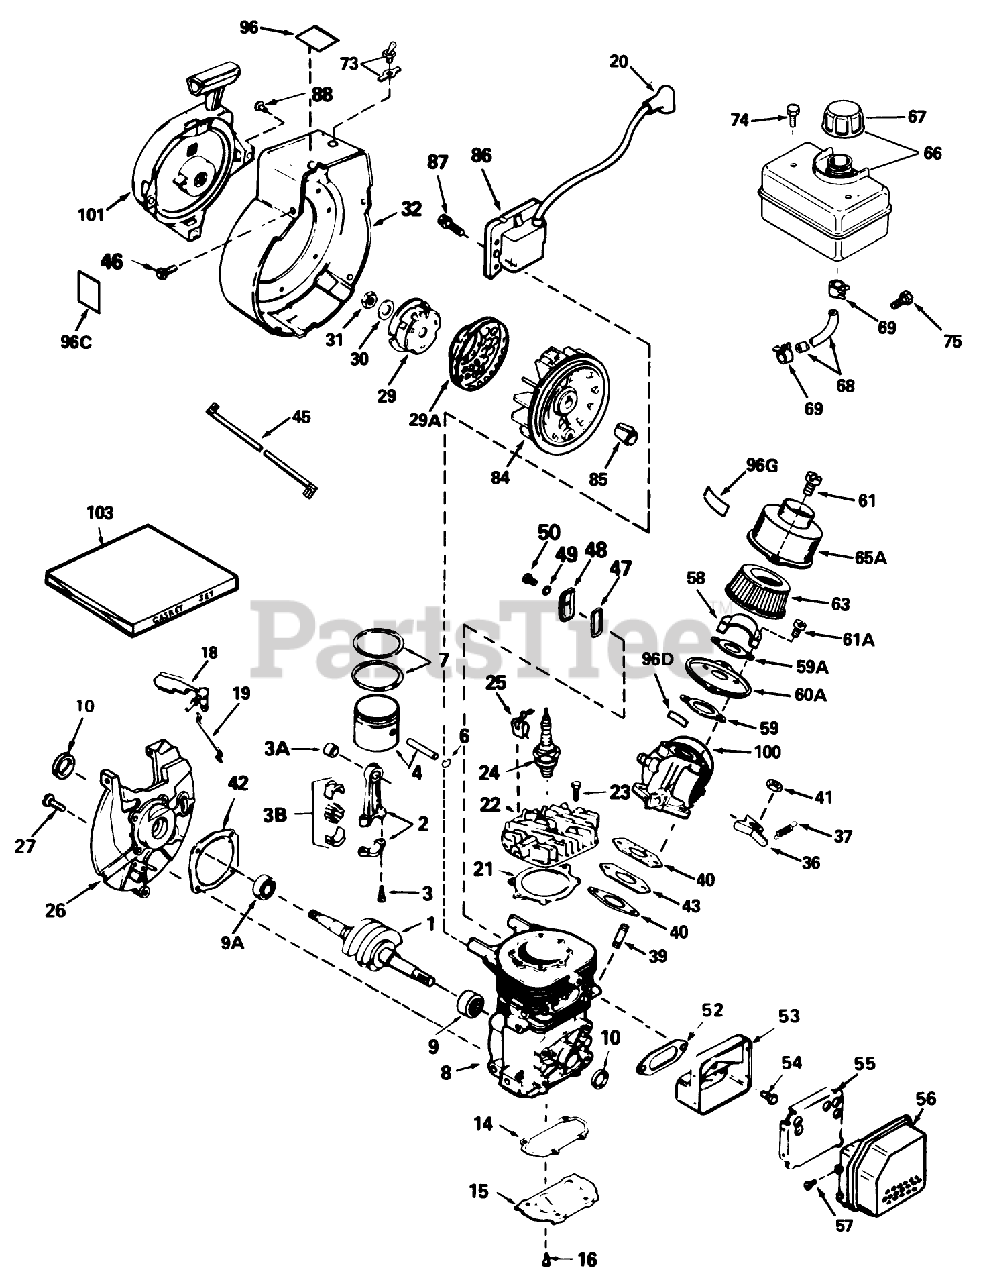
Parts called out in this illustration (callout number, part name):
1	Crankshaft
2	Rod Assy.-Connecting (Incl. Ref. #3, 3A 3B)
3	Bolt-Rod, Connecting
3A	Bearing-Cartridge
3B	Needle Bearing and Liner Set (37 Needles)
4	Piston (Incl. Ref. #43)
6	Ring-Retaning
7	Ring Set
8	Cylinder Block Assy. (Order short block if replacement is required)
9	Bearing-Cartridge
9A	Bearing-Ball
10	Seal-Oil
14	Cover
15	Plate-Cover
16	Screw (T-25, 10-24 x 1/2)
18	Vane-Air
19	Link-Governor
20	Cover-Spark Plug
21	Gasket-Head, Cylinder
22	Head-Cylinder
23	Screw (T-30, 1/4-20 x 3/4)
24	Spark Plug-Resistor (R C J 8Y)
26	Base Assy.-Blower Housing (Incl. Ref. #10)
27	Screw (T-30, 1/4-20 x 5/8)
29	Cup-Starter
29A	Screen, Air
30	Washer-Belleville
31	Nut-Flywheel
32	Housing-Blower
36	Lever-Adjusting, Rpm
37	Spring-Governor
39	Stud-Carburetor
40	Gasket-Carburetor
41	Locknut
42	Gasket-Cover, Cylinder
43	Spacer
45	Wire-Ground
46	Screw-Hex, Hd.
47	Cover-Compression, Release
48	Comp. Release Cover
49	Washer
50	Screw (T-25, 10-24 x 1/2)
52	Gasket-Exhaust
53	Base-Muffler
54	Screw (T-30, 1/4-20 x 5/8)
55	Baffle-Muffler
56	Cover Muffler
57	Screw
58	Baffle-Carburetor
59	Gasket-Air Cleaner
59A	Gasket
60A	Bracket
61	Screw
61A	Screw (10-32 x 1/2)
63	Element
65A	Cover-Air Cleaner
66	Tank Assembly-Fuel (Incl. Ref. #250 253)
67	Cap-Fuel
68	Line-Fuel
69	Clamp-Line, Fuel
73	Switch
74	Screw
75	Screw (1/4-15x7/8)
84	Flywheel
85	Blade (20 inch)
86	Solid State
87	Screw
88	Rivet-Pop (obtain locally)
96	Decal-Name
96C	Decal-Fuel Mixture
96D	Decal-Primer
96G	Decal-Air Cleaner
100	Carburetor Assembly (Incl. Ref. #40)
101	Starter-Rewind
